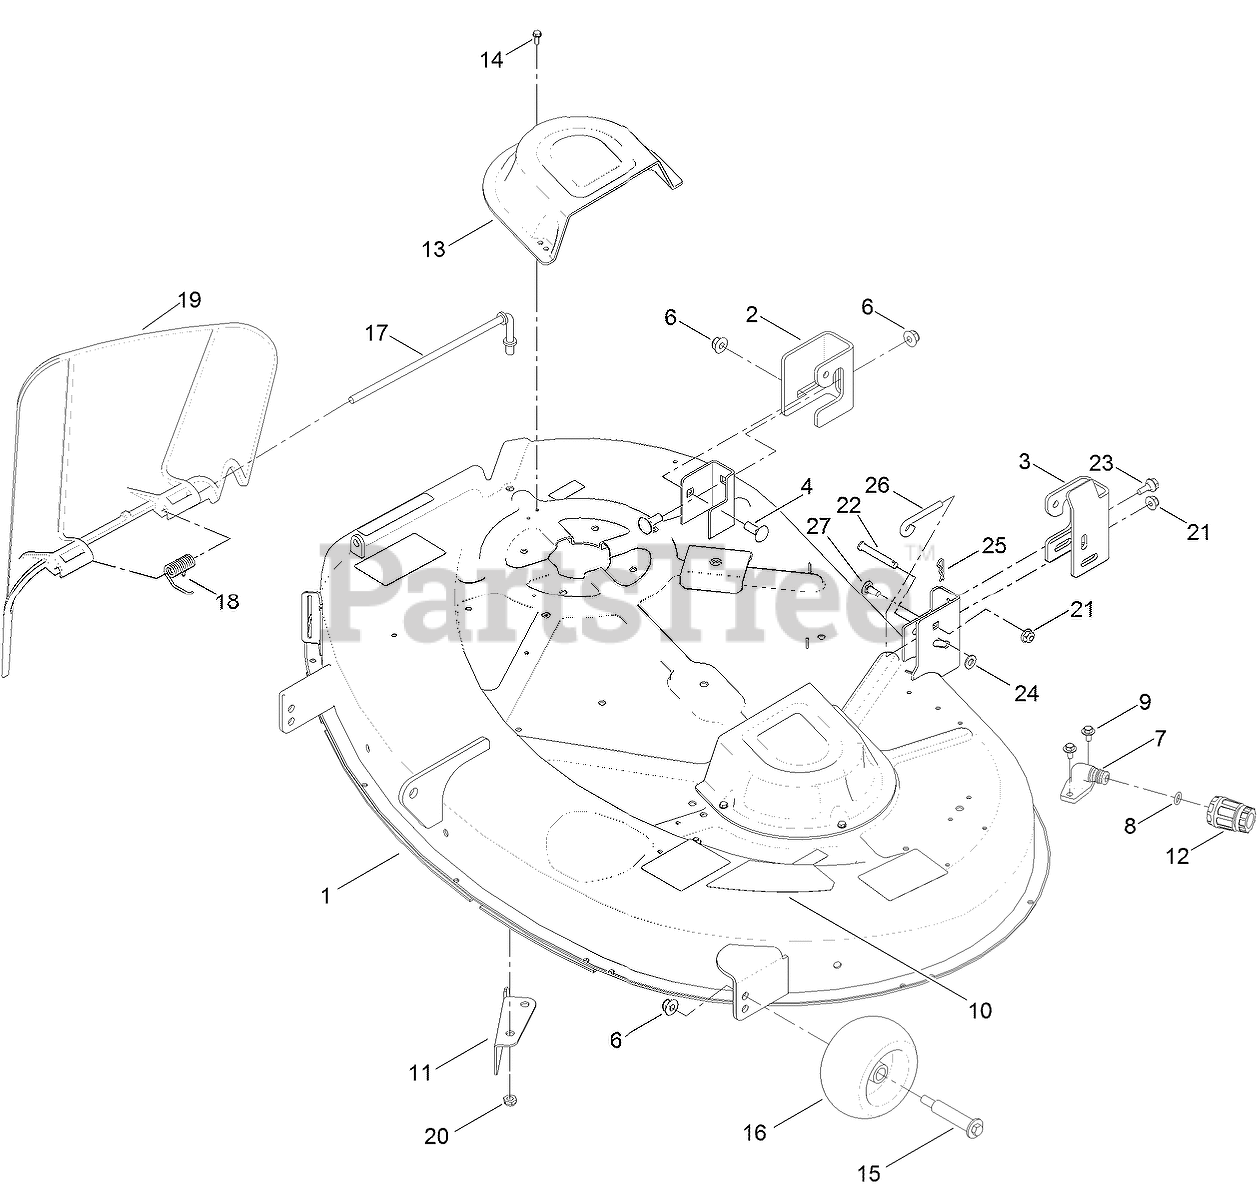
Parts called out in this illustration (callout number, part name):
1	42 INCH DECK AND DECAL ASM
2	BRACKET-HANGER, RH
3	BRACKET-HANGER, LH
4	BOLT-CARR
6	NUT-HF, NI
7	FITTING-WASHOUT
8	O-RING
9	SCREW-HHFTF
11	BAFFLE-CUTOFF
12	CONNECTOR-HOSE
13	COVER-BELT
14	SCREW-TAPTITE
15	BOLT-SHOULDER
16	ROLLER-SCALP, ANTI
17	ROD-PIVOT
18	SPRING-TORSION
19	DEFLECTOR
20	NUT-LOCK, NI
21	NUT-HF, NI
22	PIN-CLEVIS
23	SCREW-SHOULDER, HHF
24	WASHER-PLAIN
25	PIN-COTTER
26	ROD-LEVEL, DECK
27	SCREW-CARR
